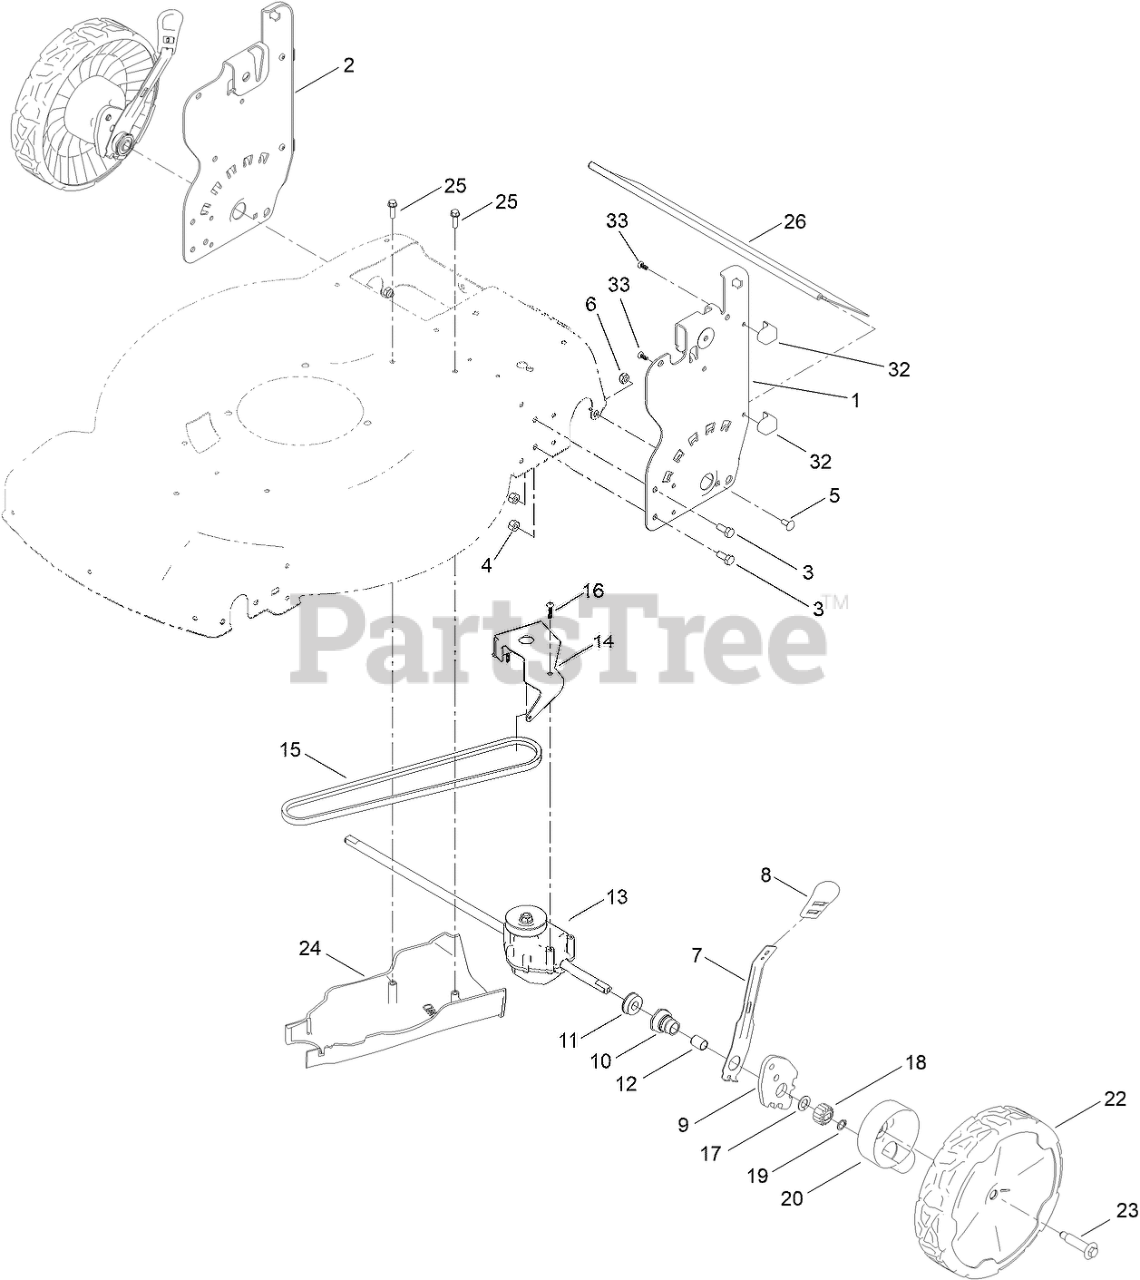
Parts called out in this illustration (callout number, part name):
1	PLATE-HOC, LH (2 HOLE)
2	PLATE-HOC, RH (2 HOLE)
3	SCREW-HH
4	NUT-HEX
5	BOLT-CARR
6	NUT-LOCK
7	ARM-SPRING
8	KNOB-HOC
9	ARM-PIVOT, REAR
10	RETAINER-BUSHING, HOC
11	BEARING-BALL
12	BUSHING-SLEEVE
13	TRANSMISSION-RWD
14	BRACKET-TRANSMISSION
15	V-BELT
16	SCREW-PLASTITE
17	WASHER-THRUST
18	GEAR-PINION, 15T
19	RING-RETAINING
20	ASM-COVER, GEAR (DK GRAY)
22	ASM-9.65" WHEEL, GEARED
23	WHEEL BOLT
24	COVER-BELT, RWD
25	SCREW-PLASTITE, HWH
26	SHIELD-TRAILING
32	PAD-SMART STOW
33	SCREW-PPH
